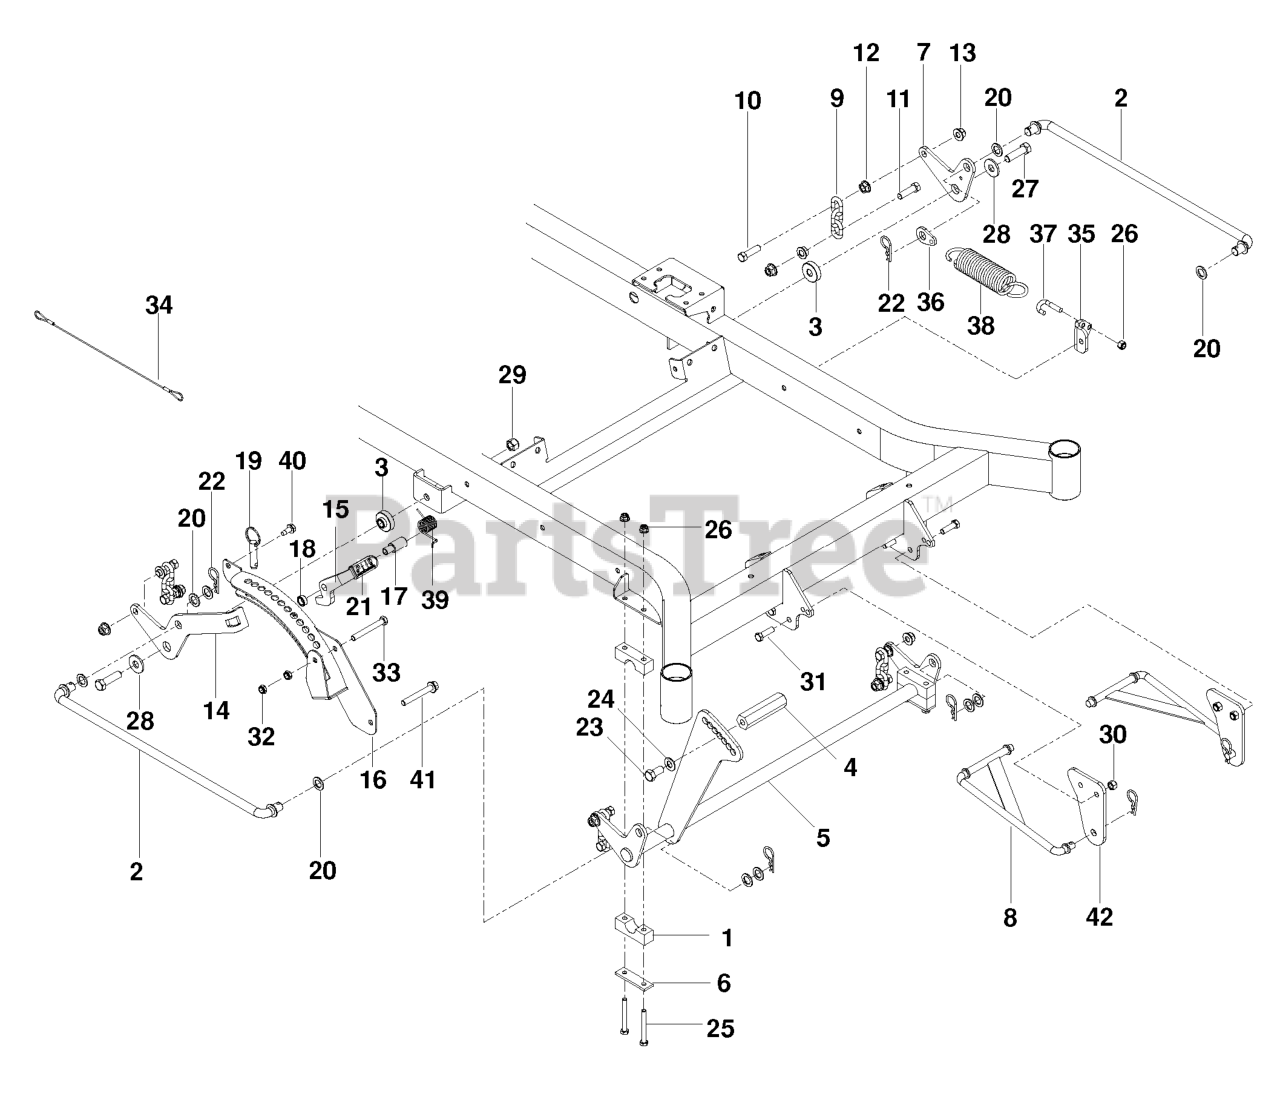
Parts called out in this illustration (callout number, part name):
1	PILLOW BLOCK
2	CROSS LINK
3	IDLER SPACER
4	PEDAL, FOOT, HEX
5	SHAFT, FT, LIFT - BLK
6	REINFORCEMENT BAR
7	BELLCRANK, RR, LIFT
8	STRUT LINKAGE
9	LIFT CHAIN - 3 LINK
10	HCS 7/16C X 1 1/2
11	HCS 7/16 - 14 X 1 3/4
12	NUT 7/16C WHIZ
13	NUT 7/16-14 HEX WHIZ LK
14	BELLCRANK, RR, RT
15	LATCH, TRANSPORT
16	HEIGHT, ADJUST, DECK
17	PIVOT, LATCH, TRANSPORT
18	SPACER, .3
19	PIN, 1/2 X 1 1/2, DETENT RING
20	BUSHING
21	GRIP, TRANSPORT-RELEASE
22	PIN, COTTER 1 3/4
23	HHCS 1/2-13 X 1
24	WASHER, 7/16 DISC SPRING
25	HCS 5/16C X 2-3/4
26	5/16-18 NYLOC FLANGE NUT
27	HCS 1/2-13 X 1 3/4 GR 8
28	WASH USS FLAT 1/2
29	NUT 1/2-13 HEX NYLOC ZD
30	NUT 3/8-16 NYLOC
31	HCS 3/8C X 1 1/4 GR5
32	NUT HEX 3/8-16 NYLON, THIN
33	HCS 3/8C X 3
35	MOUNT, SPRING
36	TAB, SPRING
37	J-BOLT
39	SPRING, TORSION
40	BOLT 5/16-18 X 3/4
41	HHFS 3/8-16 X 2 3/4
42	MOUNT, STRUT
